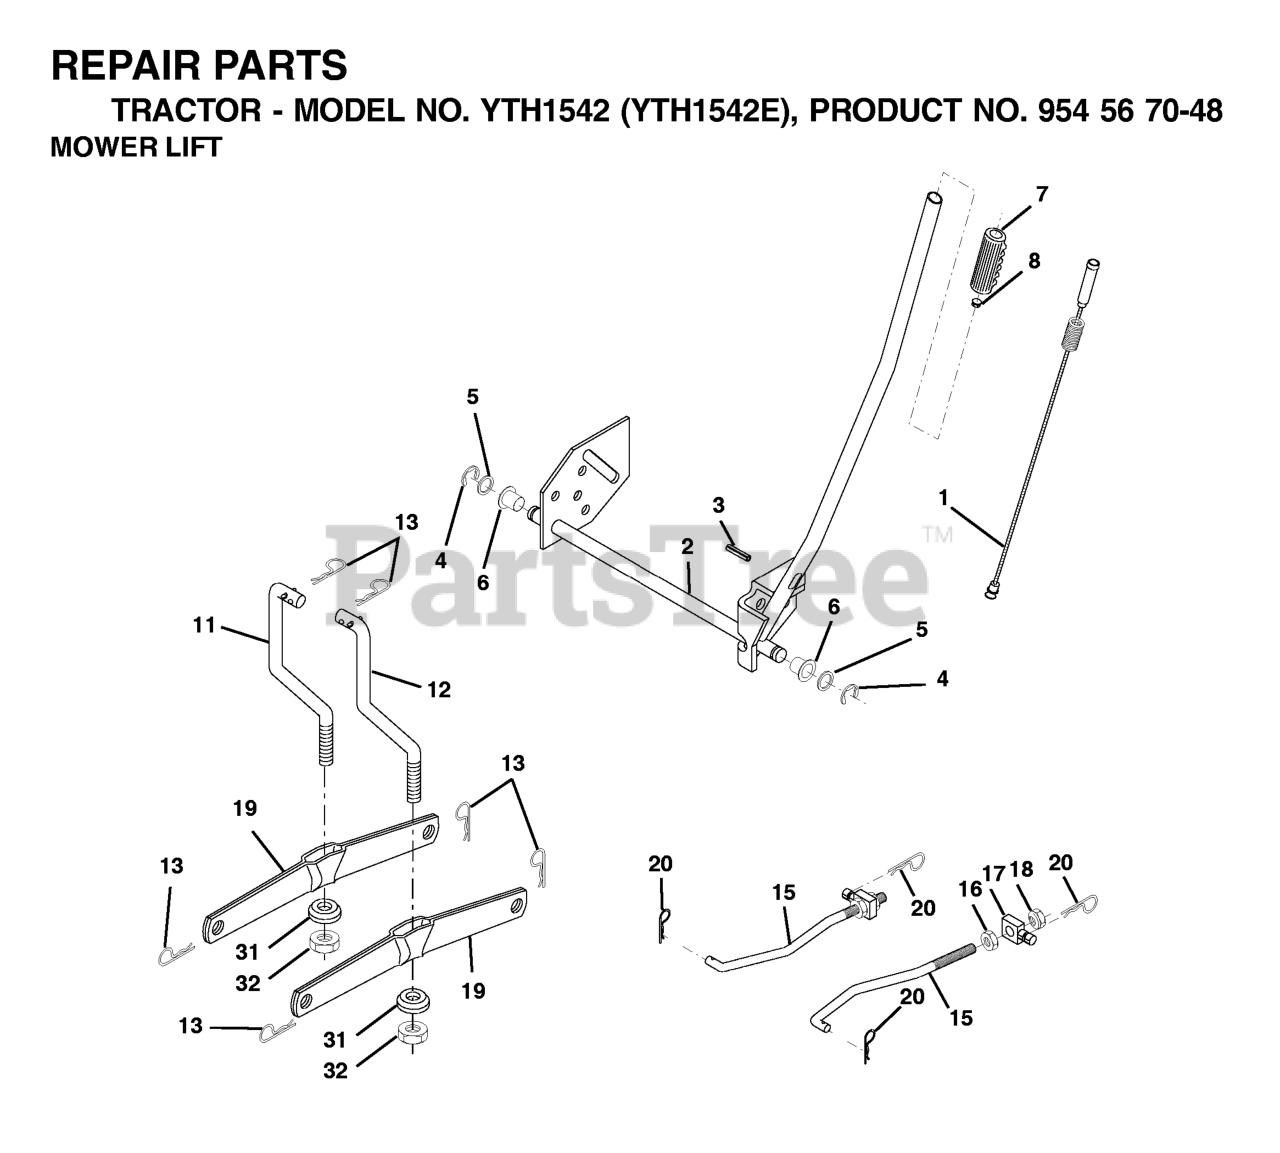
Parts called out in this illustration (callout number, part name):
1	WIRE ASM INNER W/ PLUNGER LT
2	SHAFT ASM R HANDLE
3	PIN GROOVE.
4	RETAINING RING LT
6	BEARING.NYLON
7	GRIP HANDLE
8	PLUNGER BUT KIT
11	LINK LIFT LH
12	LINK LIFT RH
13	RETAINER-SPRNG RB
15	LINK.SUSPENSION.FRONT
16	NUT.HEX.JAM.1/2-13
18	NUT.LK.W/WSH.1/2.
19	ARM.REAR.SUSPENSION
20	SPRING RETAINER
31	BEARING.PIVOT.LIFT
32	NUT CROWNLOCK 3/8-24
